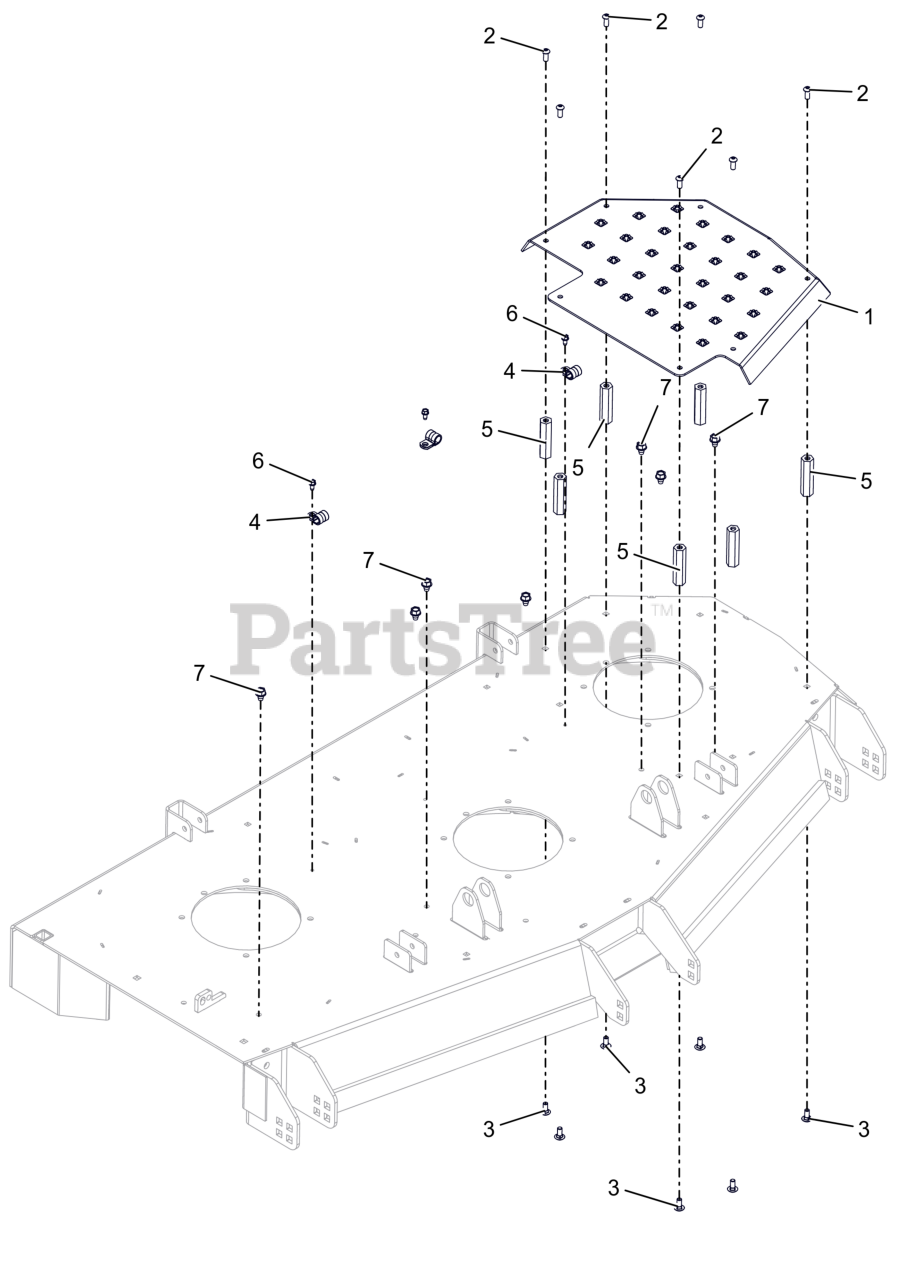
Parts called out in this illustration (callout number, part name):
1	PLATFORM, WLDMT 60 SD DECK STEP (ORANGE)
2	SCR-SKH .31-18X.75 BTNHD YWZC
3	BLT, RHSN .31-18X.75 G5 ZCC LT
4	CLAMP, CUSHIONED STEEL
5	NUT, COUPLING .31-18 X 3.00
6	SCR-TAP .25-20X.50 HWH ZCC
7	SCR,TAP .375-16X.50 HWH TR ZCC
